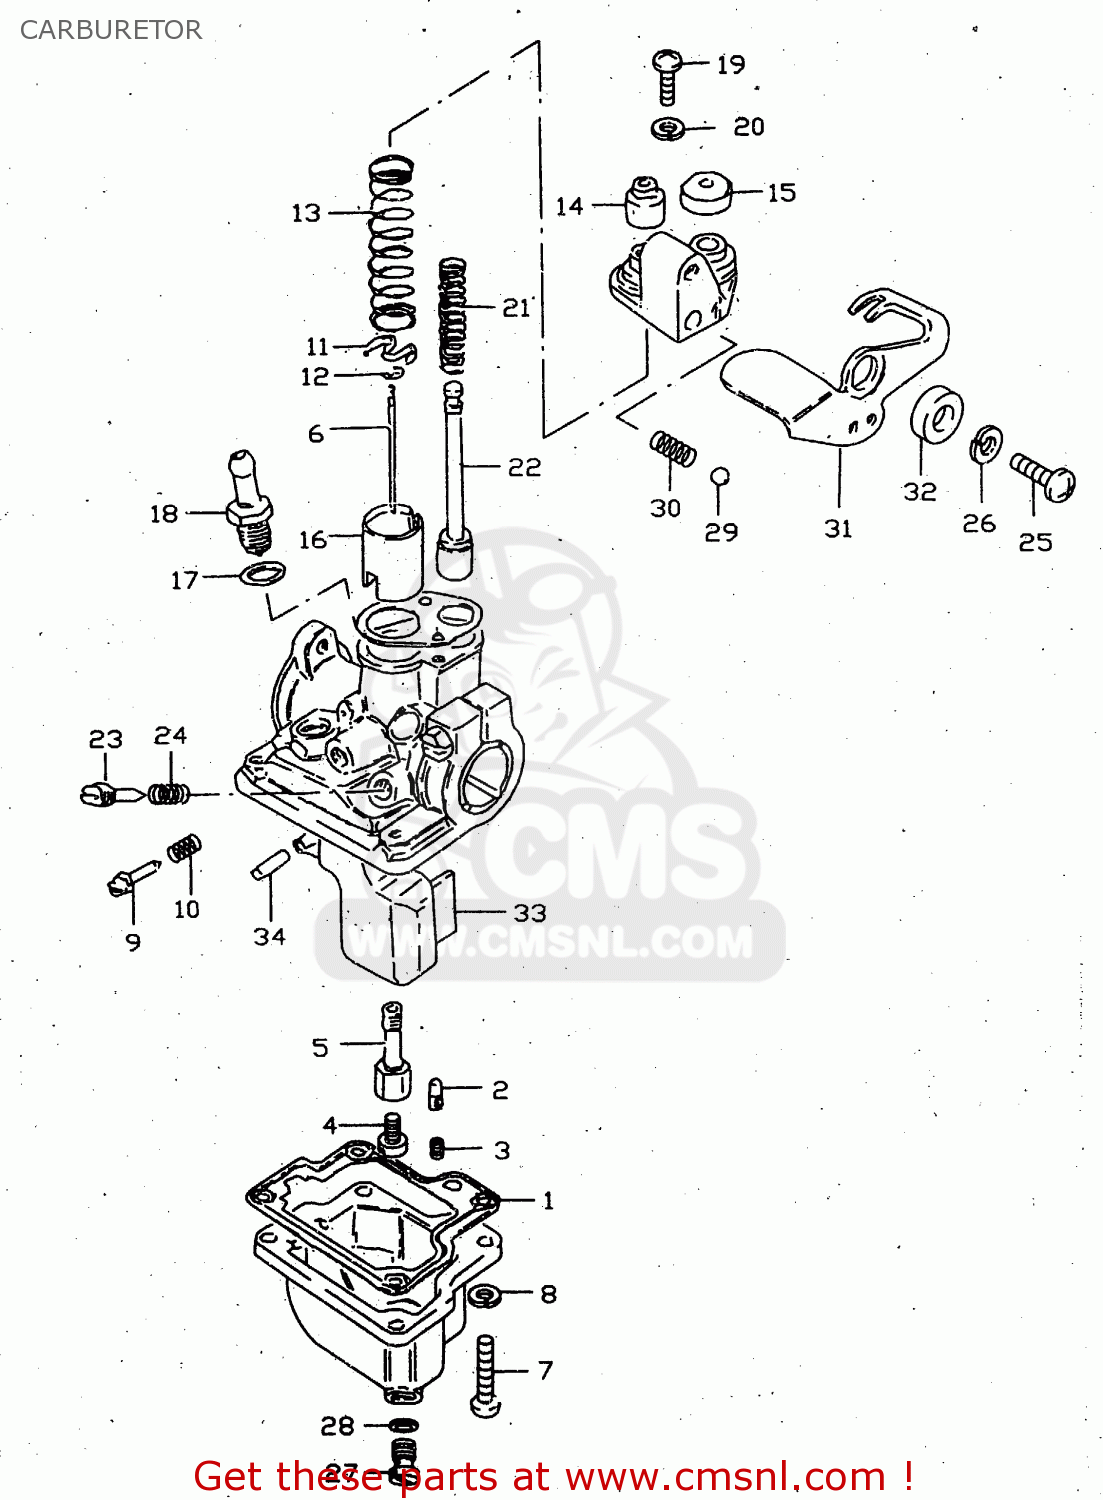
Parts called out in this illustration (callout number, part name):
1	GASKET,FLOAT CAHMBER (NAS)
2	JET,PILOT
3	JET,PILOT
4	JET,MAIN
5	JET,NEEDLE
6	NEEDLE,JET
7	SCREW
8	WASHER,LOCK
9	SCREW,THROTTLE STOP
10	SPRING
11	SEAT,THROTTLE VALVE SPRING
12	CLIP,NEEDLE
13	SPRING,THROTTLE VALVE
14	CAP
15	RUBBER,THROTTLE VALVE CAP
16	VALVE,THROTTLE
17	GASKET,THRO VALVE INSPECTION (NAS)
18	VALVE ASSY,NEEDLE
19	SCREW
20	WASHER,LOCK
21	SPRING
22	VALVE,STARTER
23	SCREW,AIR
24	SPRING
25	SCREW
26	LOCK WASHER
27	PLUG
28	GASKET,DRAIN,PLUG (NAS)
29	BALL,STARTER SHAFT
30	SPRING,STARTER SHAFT
31	LEVER,STARTER
32	RING,CARBURETOR STARTER
33	FLOAT
34	PIN,FLOAT
